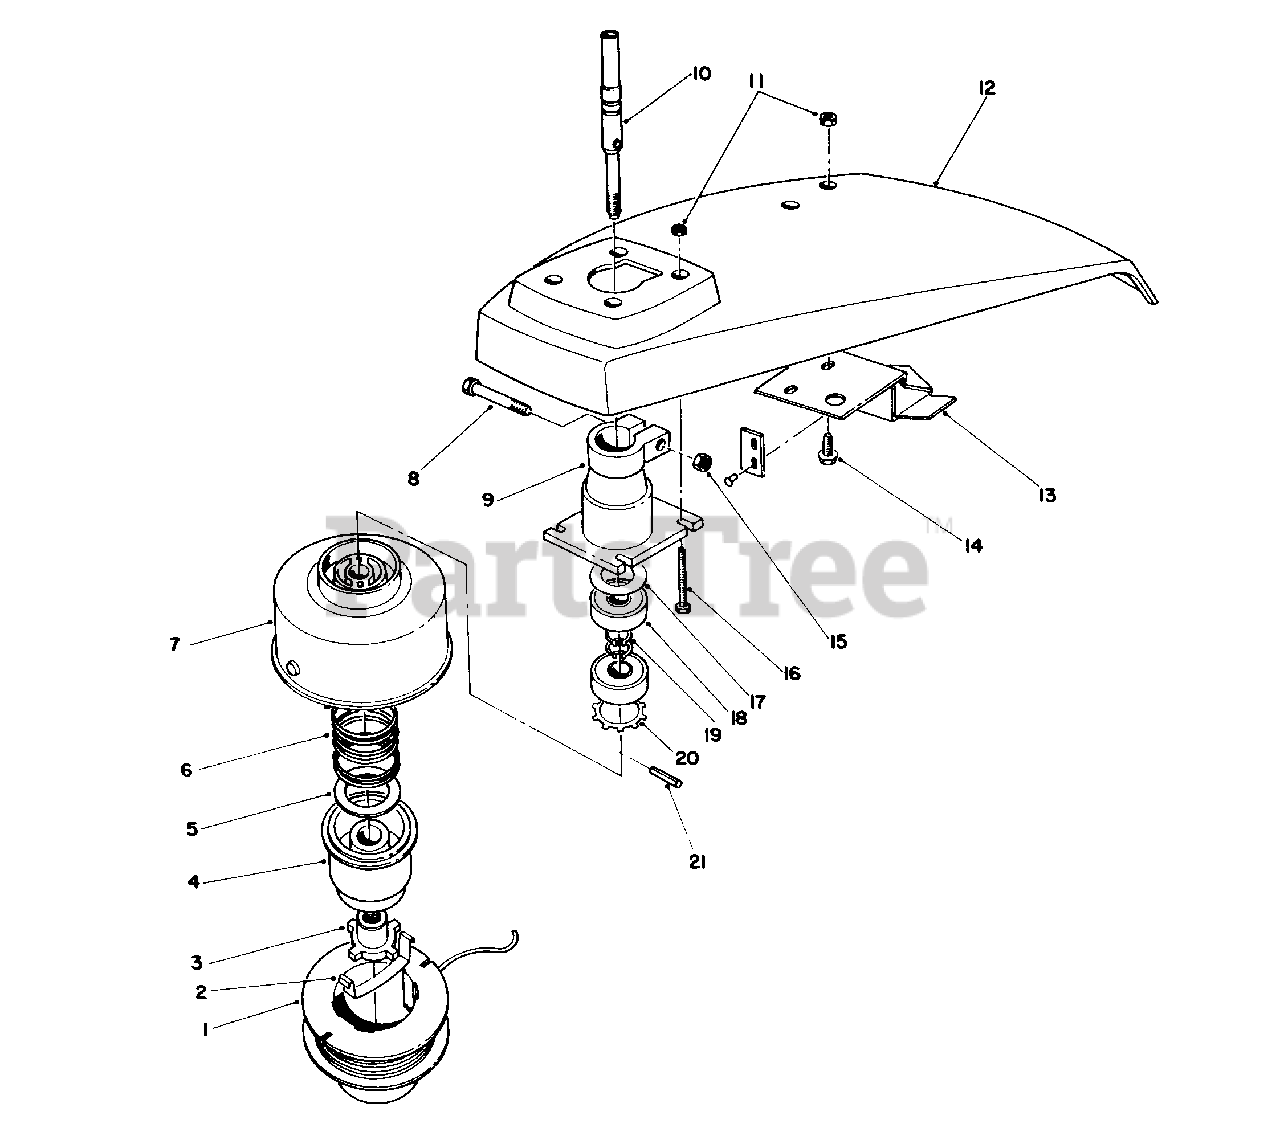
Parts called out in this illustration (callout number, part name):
1	Spool-Prewound .08 Dia. 38' (Incl. Ref. #2)
2	Saddle-Spool Cap
4	Core-Spool
6	Spring-Compression
7	Drum w/Eyelet
8	Screw-Hex. Hd.
9	Housing-Bearing (Incl. Ref. #10, 17-21)
10	Shaft-Power
11	Nut-Lock
13	Bracket & Knife Blade
14	Screw-Hex. Washer Hd.
15	Nut-Lock
16	Screw-Hex. Washer Hd.
18	Bearing-Ball
19	Ring-Retaining
20	Spring-Grip
21	Pin-Coil
